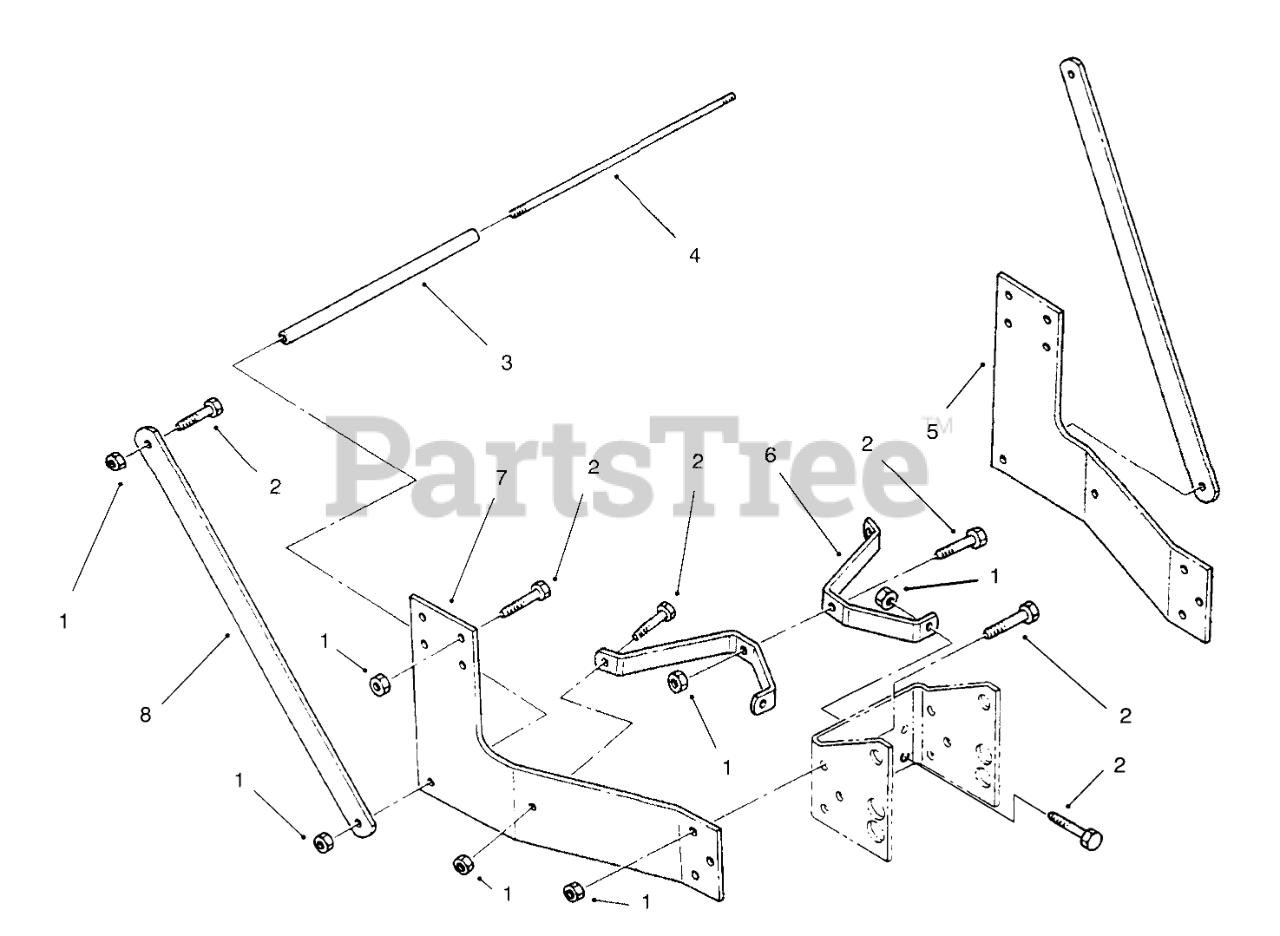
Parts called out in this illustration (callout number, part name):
1	NUT-LOCK, NI
2	SCREW-HH
3	SUPPORT TUBE
4	SUPPORT ROD
5	Bracket-LH.
6	Brace-Center
7	Bracket R.H.
8	Brace
